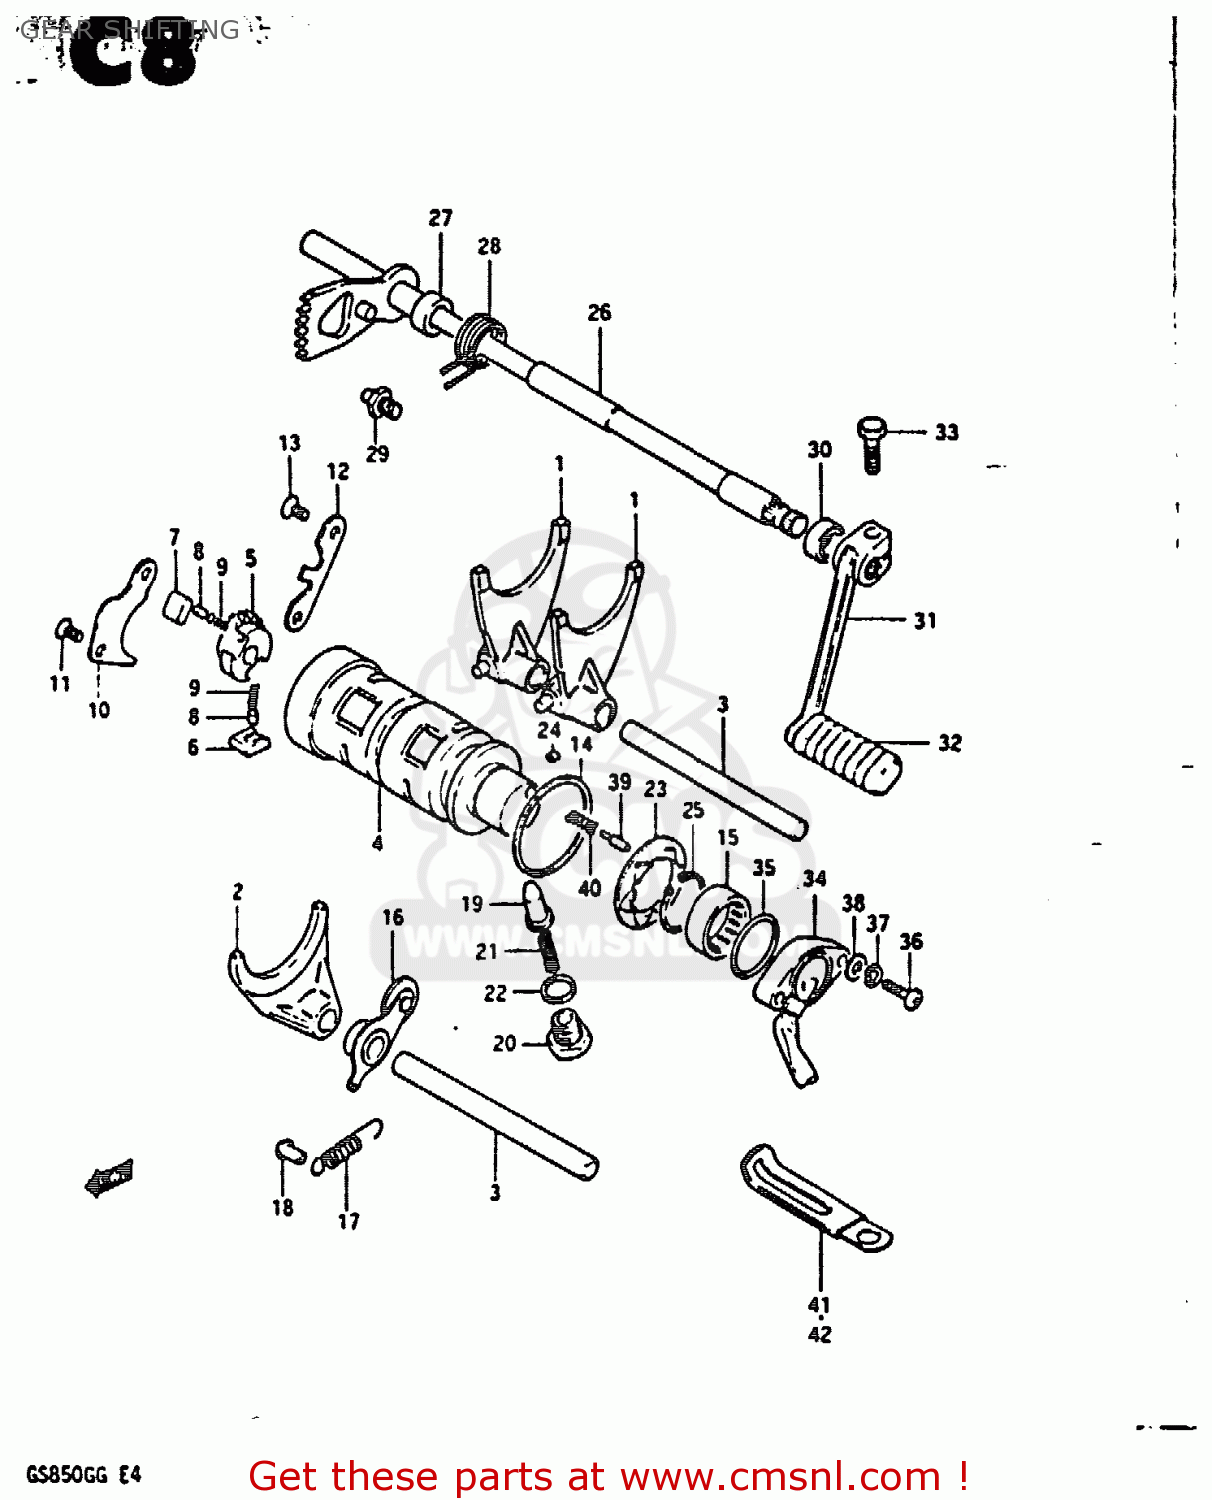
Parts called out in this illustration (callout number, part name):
1	FORK,GEAR SHIFT NO.1
2	FORK,GEAR SHIFT NO.3
3	SHAFT,GEAR SHIFT FORK
4	CAM,GEAR SHIFT
5	GEAR,GEARSHIFT CAM DRIVE
6	PAWL,GEAR SHIFT NO.1
7	PAWL,GEAR SHIFT NO.2
8	PIN(5X8)
9	SPRING
10	LIFTER,GEAR SHIFT PAWL
11	SCREW
12	GUIDE,GEAR SHIFT CAM
13	SCREW
14	WASHER(40X45X1)
15	BEARING(25X32X12)
16	STOPPER,GEAR SHIFTING
17	SPRING
18	RIVET
19	STOPPER,GEAR SHIFT CAM NO.2
20	HOLDER,GEAR SHIFT CAM STOP SPR
21	SPRING
22	GASKET(14X19.2X2) (NAS)
23	PLATE,GEAR SHIFT CAM STOPPER
24	PIN 4X6
25	CIRCLIP,25MM
26	SHAFT,GEAR SHIFT
27	SPACER (12X20X12)
28	SPRING
29	STOPPER,GEAR SHIFT CAM
30	OIL SEAL
31	LEVER ASSEMBLY,GEAR SHIFTING
32	RUBBER,PEDAL
33	BOLT
34	TERMINAL BASE ASSY,GEAR SHIFT
35	O-RING (D:2.4 ID:26.2)
36	SCREW
37	LOCK WASHER
38	WASHER
39	PIN(5X15.5)
40	SPRING
41	CLAMP
42	CLAMP
